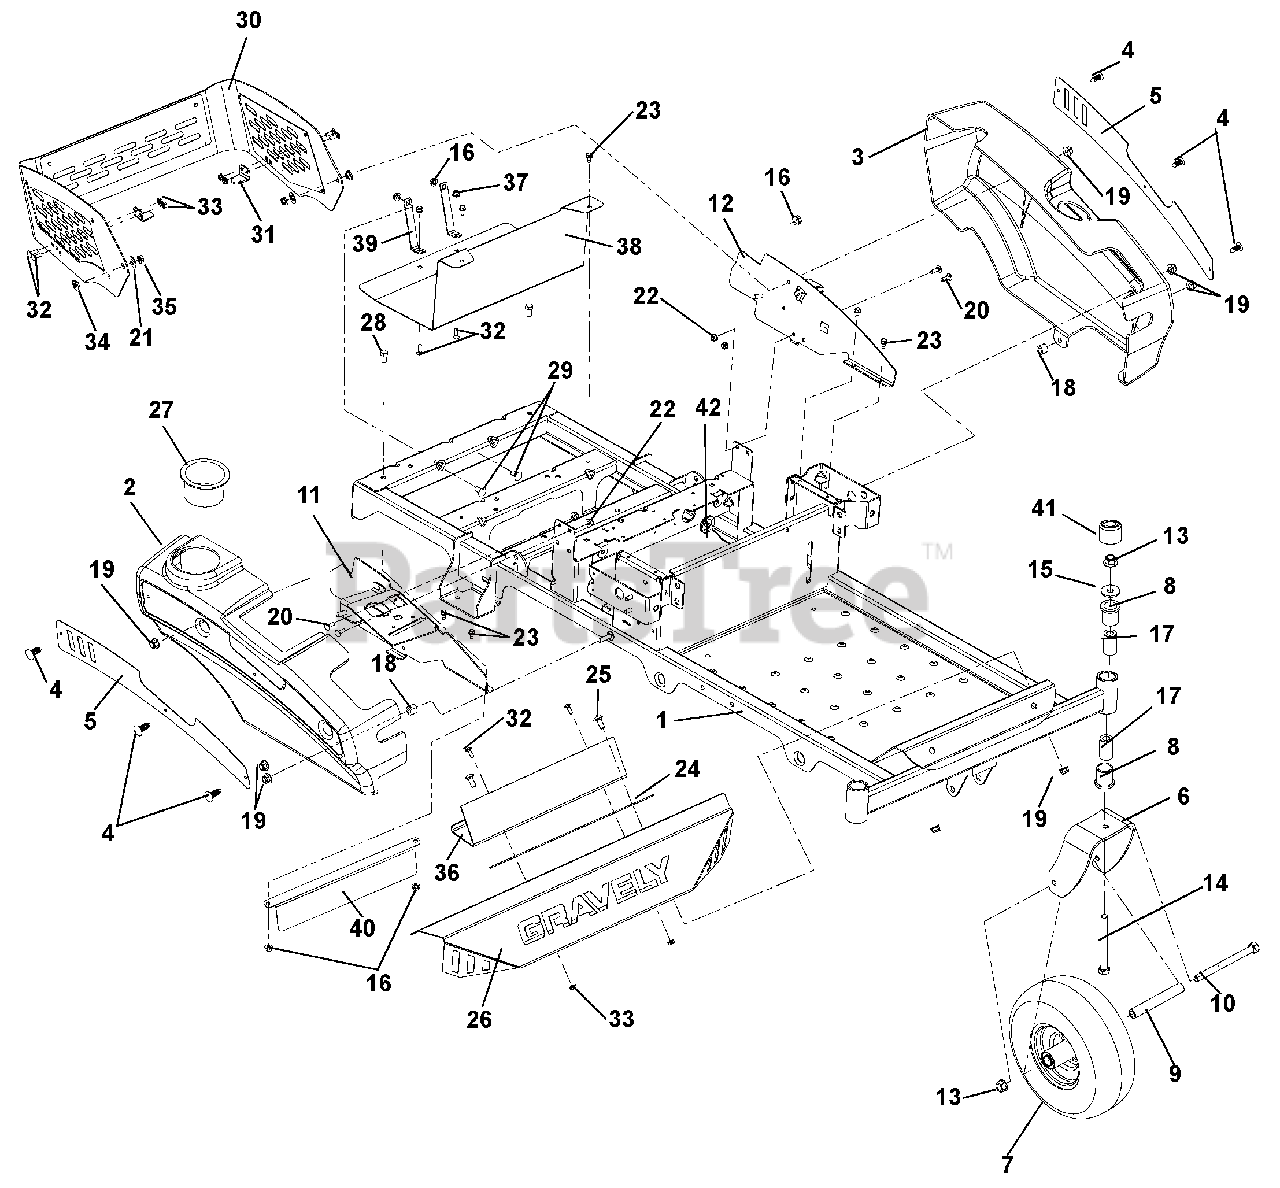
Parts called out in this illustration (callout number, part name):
1	Weldment, Frame
2	Fender, Right Hand
3	Fender, Left Hand
4	Rivet, Nylon
5	Plate, Fender
6	Fork, Caster
7	Tire/Wheel Assembly, 11 x 4-5
8	Bushing, Flange 1.00 x 1.25 x 1.50 x 1.50
9	Spacer, Wheel
10	Bolt, Hex .50-13 x 6.50
11	Weldment, Fender Mount Right Hand
12	Weldment, Fender Mount Left Hand
13	Nut, Locking, Top, Flange .50-13
14	Bolt, Hex .50-13 x 5.00
15	Washer, Flat Steel .511 x 1.441 x .125
16	Nut, Locking, Top, Flange .38-16 (915328)
16	Nut, Locking, Top, Flange .38-16 (915327)
17	Spacer, Caster
18	Bushing, Sleeve .391 x .688 x .52
19	Nut, .31-18 Nyloc Flange
20	Bolt, Round Head Square Neck .25-20 x .75
21	Washer, Flat, Nylon .52 x 1.00 x .08
22	Nut, .25-20 Nyloc Flange
23	Screw, Tapping .25-20 x .50 Hex Washer Head Thread
24	Grip, Adhesive (1" x 16" BLK)
25	Bolt, Round Head Square Neck .31-18 x .75
26	Foot Rest
27	Cupholder
28	Bolt, Hex .38-16 x 1.00
29	Bolt, Round Head Square Neck .31-16 x .75
30	Assembly, Engine Wrap
31	Bracket, Engine Wrap Foot
32	Bolt, Round Head Square Neck .25-20 x .50
33	Nut, Center Lock Flange .25-20
34	Bushing, Flange .325 x .499 x .3 x .875
35	Nut, Center Lock Flange .31-18
36	Plate, Back Foot Rest
37	Nut, Locking Top Flange .25-20
38	Guard, Heat Shield (ZT)
39	Strap, Heat Shield (ZT)
40	Guard, Hot Surface (ZT)
41	Cap, Dust
42	Grommet 1.0 I.D. x1.38 O.D.
